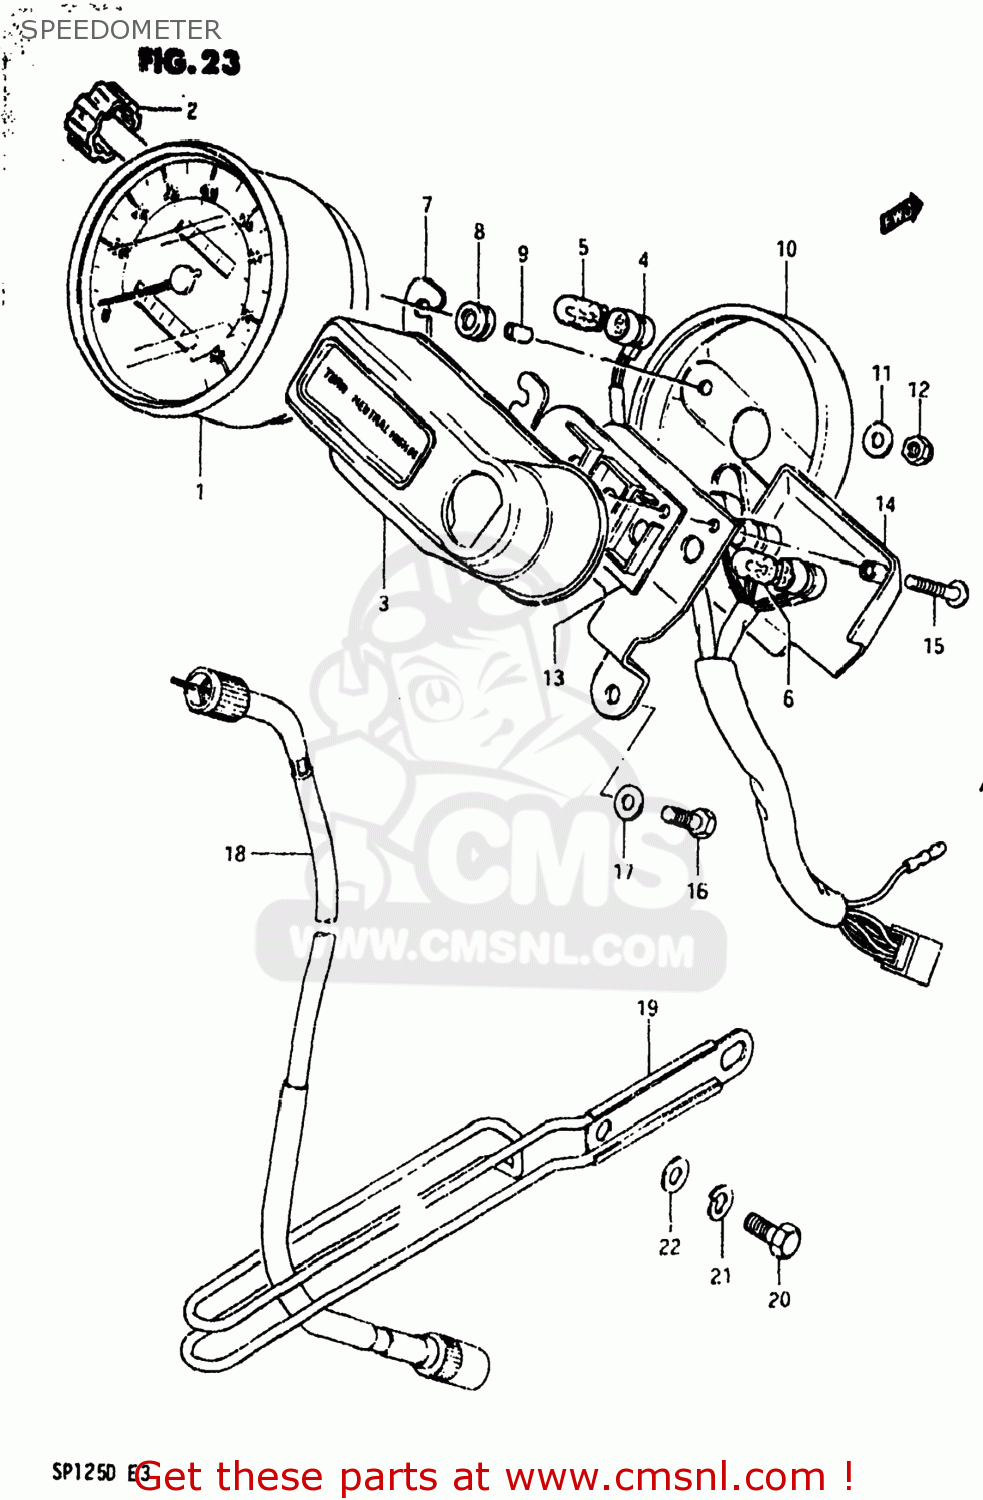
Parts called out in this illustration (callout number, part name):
1	SPEEDOMETER ASSEMBLY
2	KNOB,TRIP
3	CASE,PILOT BULB
4	SOCKET,METER
5	BULB(6V,3W)
6	BULB(6V1.7W,STANLEY,A61A)
7	BRACKET,METER
8	CUSHION,METER
9	SPACER,METER
10	BRACKET,SPEEDOMETER,UNDER
11	WASHER,METER
12	NUT
13	HOLDER,SOCKET
14	COVER,PILOT BOX
15	SCREW
16	BOLT
17	WASHER
18	CABLE ASSEMBLY,SPEEDOMETER
19	GUIDE,CABLE
20	BOLT 8X12
21	LOCK WASHER
22	WASHER
